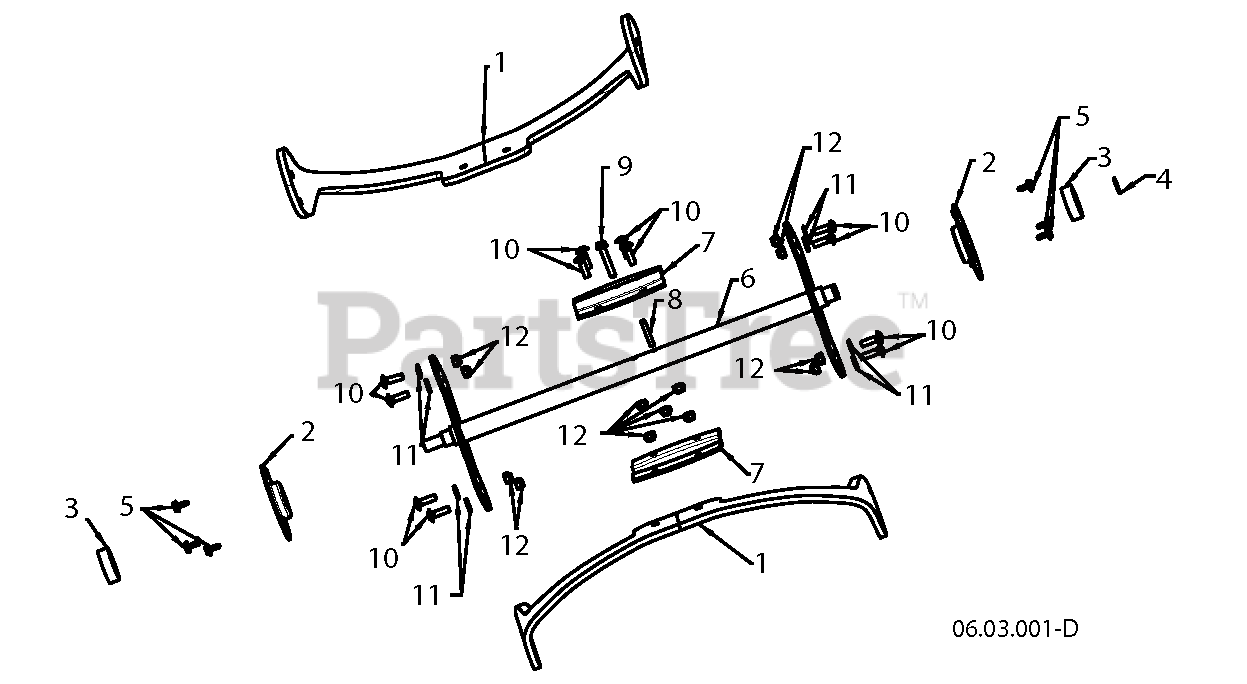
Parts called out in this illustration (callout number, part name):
1	AUGER.BLADE.SS.SNOW
2	SUPPORT.BEARING.SINGLE.STAGE.B
3	BEARING.BALL.MANDREL
4	RETAINING RING LT
6	WELDMENT.AUGER.SINGLE.STAGE.BL
7	PLATE.CENTER.BLADE.BLACK
8	PIN.ROLL.3/16 X 1-1/4
10	BOLT.CARRIAGE.1/4-20 X 7/8
12	NUT
